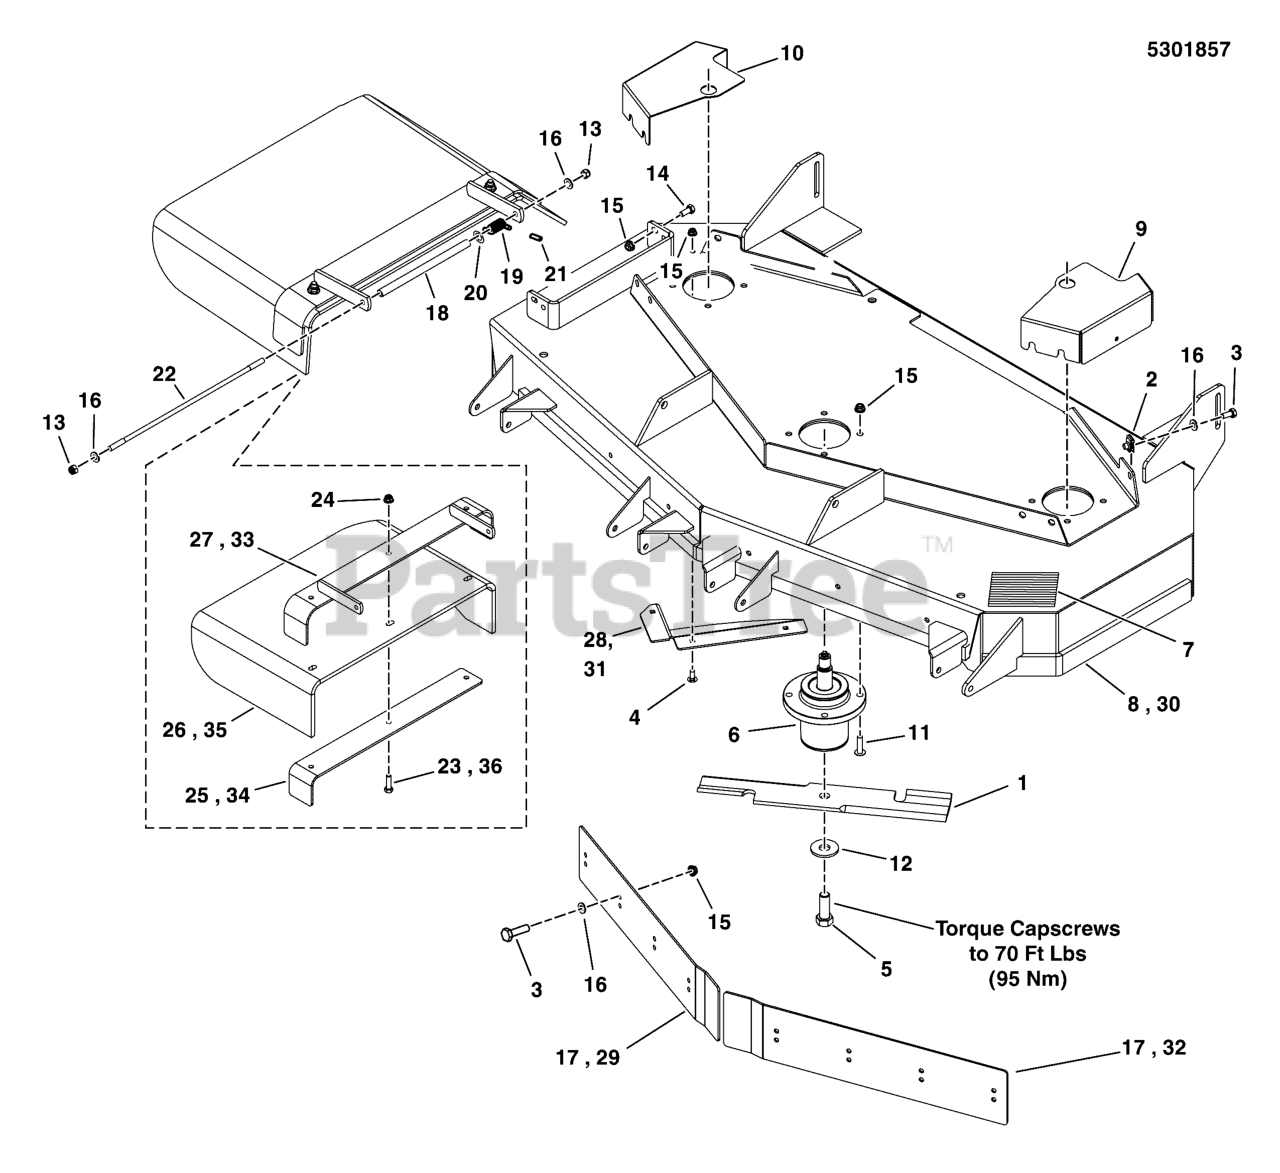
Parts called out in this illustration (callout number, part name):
1	BLADE, 18, SET OF 3
2	BODY CLIP, 5/16-18-7GA MATERIAL
3	BOLT, 5/16-18 X 3/4 GD5
4	BOLT, 5/16-18 X 3/4, CARRIAGE
5	BOLT, 5/8-11 X 1-3/4 GD8
6	ASSM, SPINDLE, LOW PROFILE
7	SAFETY WALK, 4.00 X 7.50
8	DECK SHELL W/ DECALS (5405562B)
9	GUARD, 52" DECK, IS2000 - LH - RED
10	GUARD, 52" DECK, IS2000 - RH - RED
11	BOLT, 5/16-18 X 1 1/4 FLANGE
12	WASHER, 5/8 GRADE 8, YZ
13	NUT, 5/16-18 HEX NYLON LOCK
14	BOLT, 5/16-18 X 1-1/4 GD5 YZ
15	NUT, 5/16-18 HEX NYLOCK FLANGE
16	WASHER, 5/16" SAE
17	BAFFLES. FRONT DISCHARGE, 52 YAN - BLK
18	TUBE, 1/2 X 3/8 BLACK POLY, 8.00 LG
19	SPRING, TORSION
20	WASHER, 5/16 FENDER
21	CAP, PROTECTOR, .120 ID
22	ROD, 5/16 X 13.75, TBE
23	BOLT, 3/8-16 X 1-1/2" GD5 CZ
24	NUT, 3/8-16 HEX NYLOCK FLANGE
25	SUPPORT, DISCHARGE CHUTE, 44/48/52 - BLK
26	CHUTE, DISCHARGE, RUBBER, 44/48/52
27	WELD, MOUNT, DISCHARGE CHUTE - BLK
28	PLATE, DEFLECTOR, 52"- BLK
29	BAFFLE, FRONT DISCHARGE - RH
30	DECK SHELL W/DECALS, 52, SDCE (5407538B)
31	PLATE, DEFLECTOR, 52" - BLACK
32	BAFFLE, FRONT DISCHARGE - LH
33	WELD, MOUNT, DISCHARGE CHUTE - BLK
34	SUPPORT, DISCHARGE CHUTE - BLK
35	CHUTE, RUBBER DISCHARGE (5413500)
36	BOLT, 3/8-16 X 1-1/2, CARRIAGE, GD5, CZ
